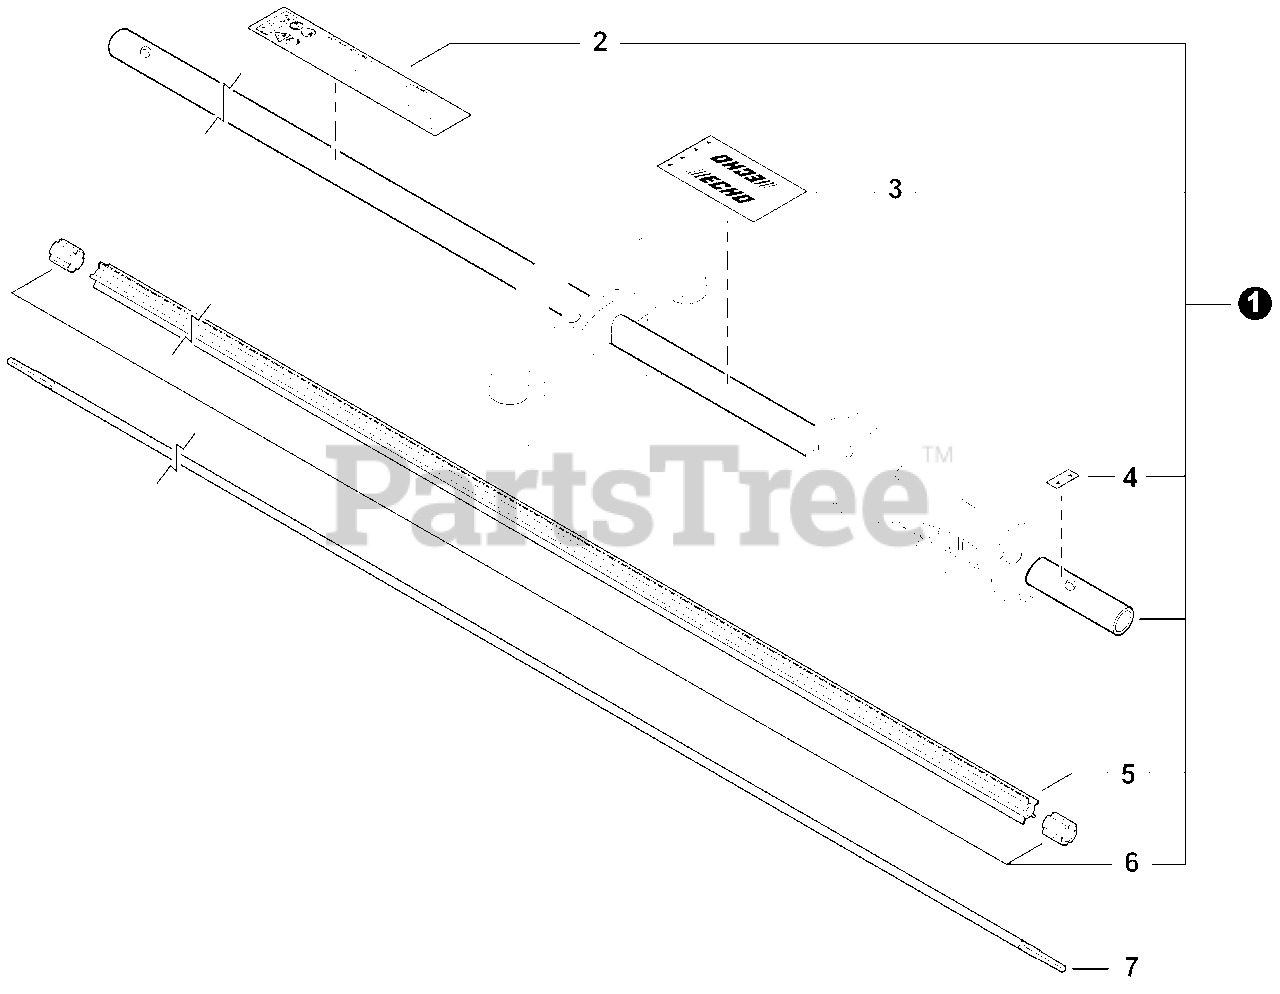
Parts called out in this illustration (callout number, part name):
1	MAIN PIPE ASSY
2	LABEL, CAUTION
3	LABEL, HANDLE LOCATION
4	LABEL - ALIGNMENT
5	LINER, FLEXIBLE 21.6×1420
7	DRIVESHAFT - FLEXIBLE L= 1522
